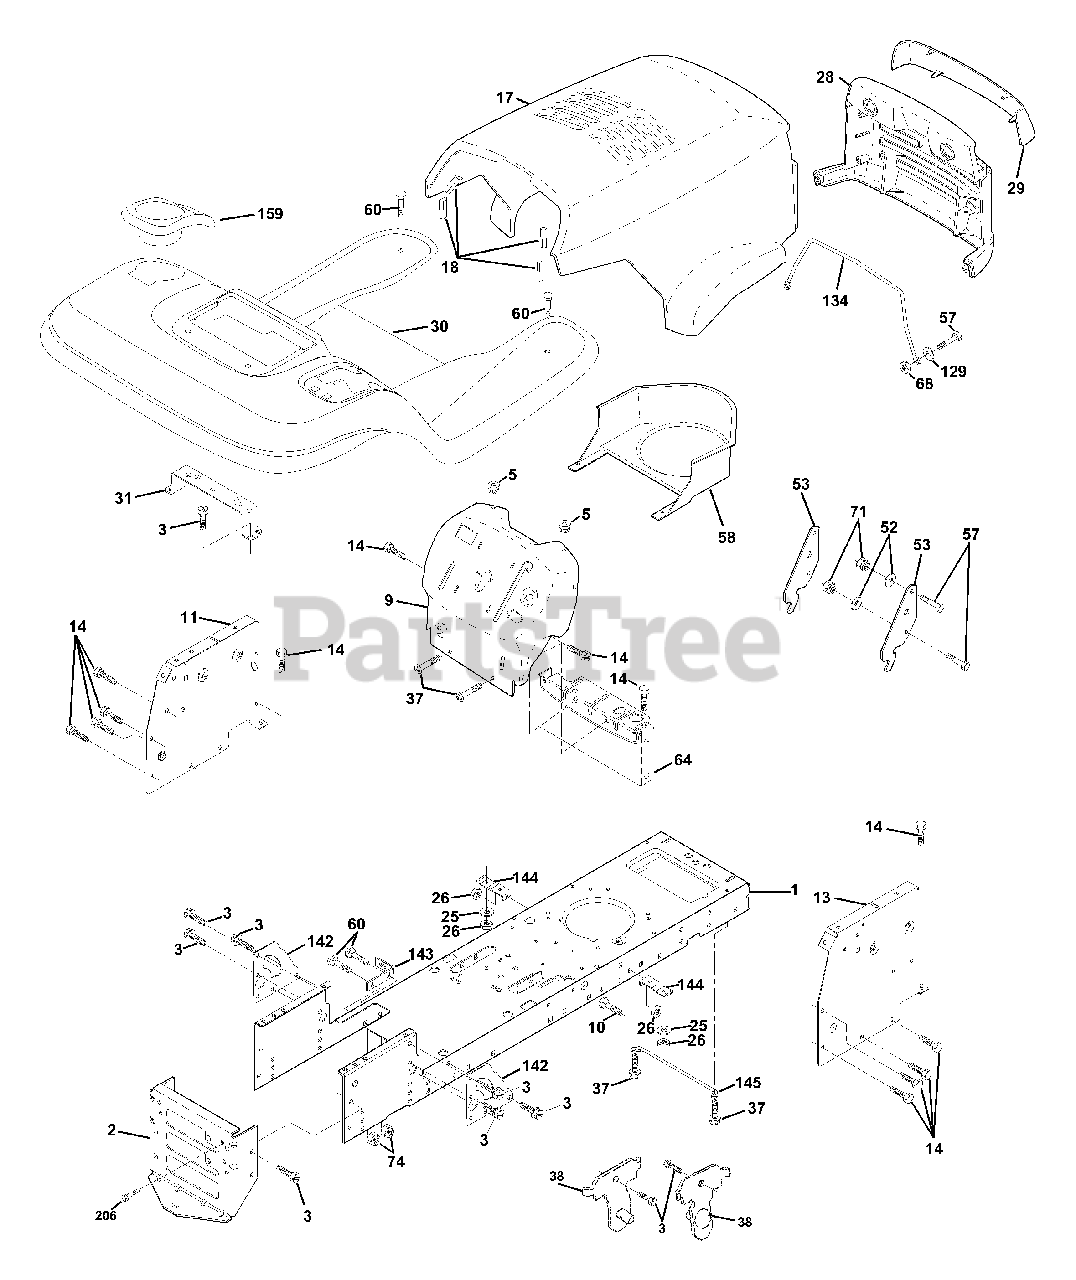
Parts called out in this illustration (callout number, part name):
1	Chassis Stamping
2	Drawbar, 12 Ga.
3	Screw Thdrol 3/8-16x3/4 Ty-tt
5	Bumper Hood/Dash
9	Dash Slkscr
10	Bolt Carriage 3/8-16 x 1
11	Panel Dash Lh
13	Panel Dash Rh
14	Screw Thdrol 3/8-16x1/2 Ty-tt
17	Hood LT/PL Husqvarna
18	Bumper Hood
25	Washer 13/32 X 13/16 X 12 Ga
26	Nut Lock Hex W/Ins 3/8-16 Unc
28	Grille LT/PL Husqvarna
29	Lens LT/PL Husqvarna
30	Fender Footrest STLT Pnt
31	Bracket Support Fender
37	Screw Thdrol 6/16-18 x 1/2 TYT
38	Bracket Asm Pivot Mower Rear
52	Washer 9/32 x 7/8 x 16 Ga.
53	Bracket Pnt. Pick off LT/PL Husqvarna
57	Bolt Hex 1/4-20 x 3/4
58	Air Duct Engine P/L
60	Bolt Rdhd Sqnk 3/8-16unc x 3/4
64	Dash Lower STLT
68	Nut Keps Hex 1/4-20unc
71	Nut Cronwn Lock 1/4-20 Unc Blk D
74	Nut Crownlock 3/8-16 UNC
129	Washer 9/32 x 5/8 x 16 Ga.
134	Rod Support Hood LT/PL Husq.
142	Plate Reinforcement STLT
143	Bracket Swaybar Chassis
144	Bracket Pnt Footrest STLT
145	Rod Pivot Chassis/Hood
159	Cupholder Stlt Grey
206	Bolt Shoulder 5/16-18 TT
